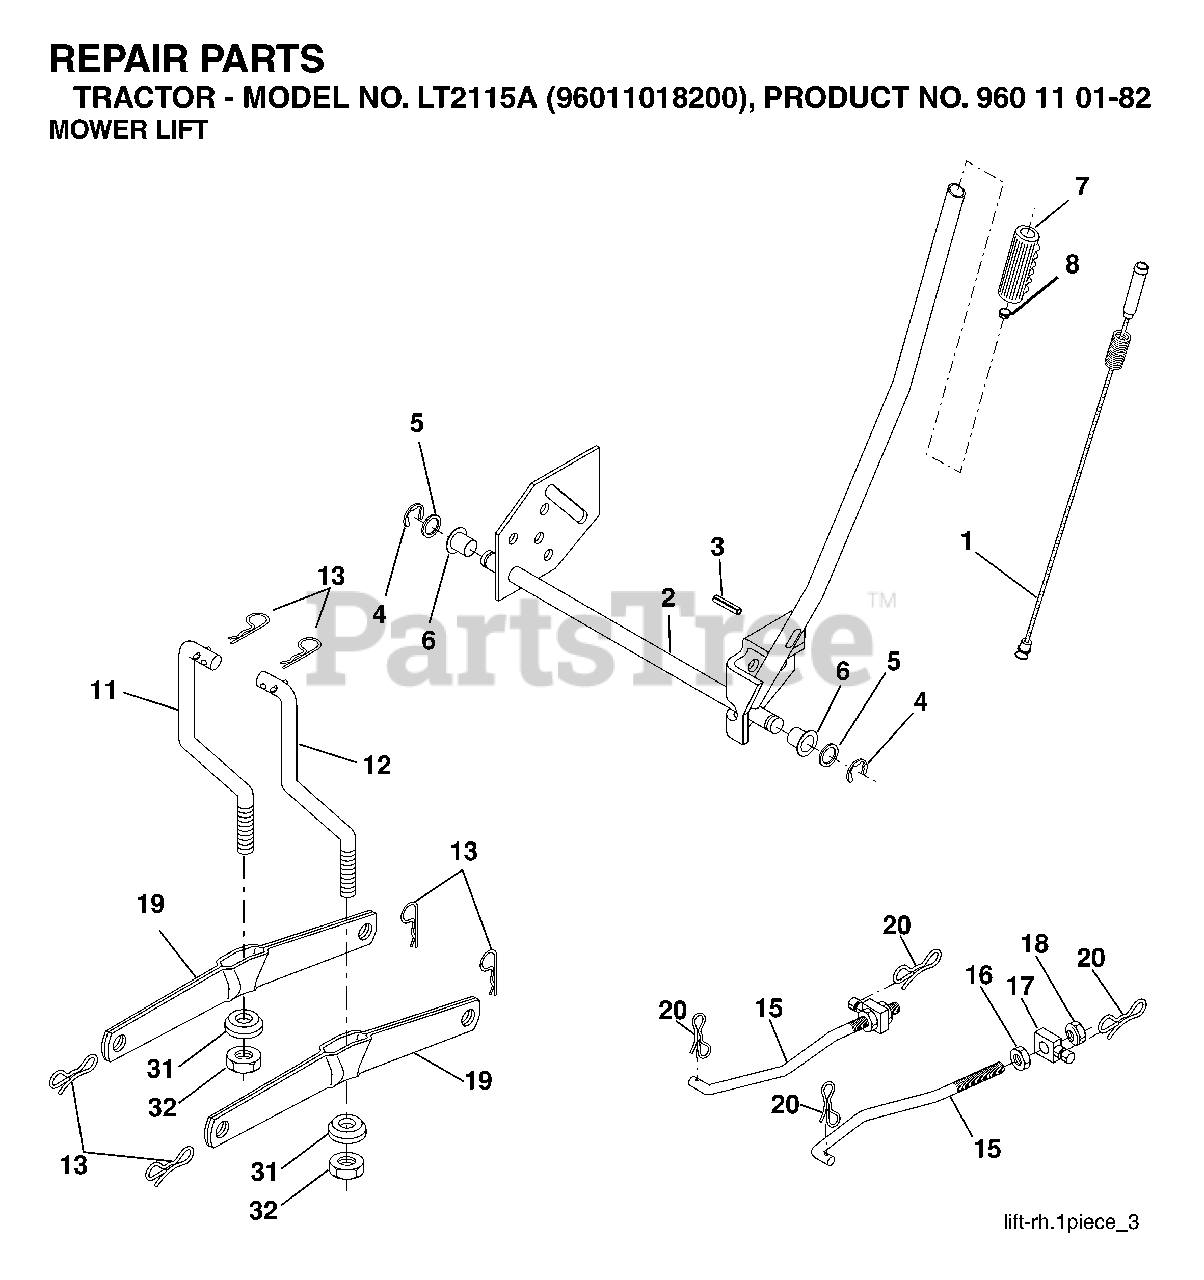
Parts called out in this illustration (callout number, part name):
4	RETAINING RING LT
6	BEARING.NYLON
7	GRIP
11	LINK LIFT LH
12	LINK LIFT RH
13	RETAINER-SPRNG RB
15	LINK.SUSPENSION.FRONT
16	NUT
18	NUT
19	ARM.REAR.SUSPENSION
20	PIN.COTTER.7/16.BOW TI
31	BEARING.PIVOT.LIFT
32	NUT CROWNLOCK 3/8-24
